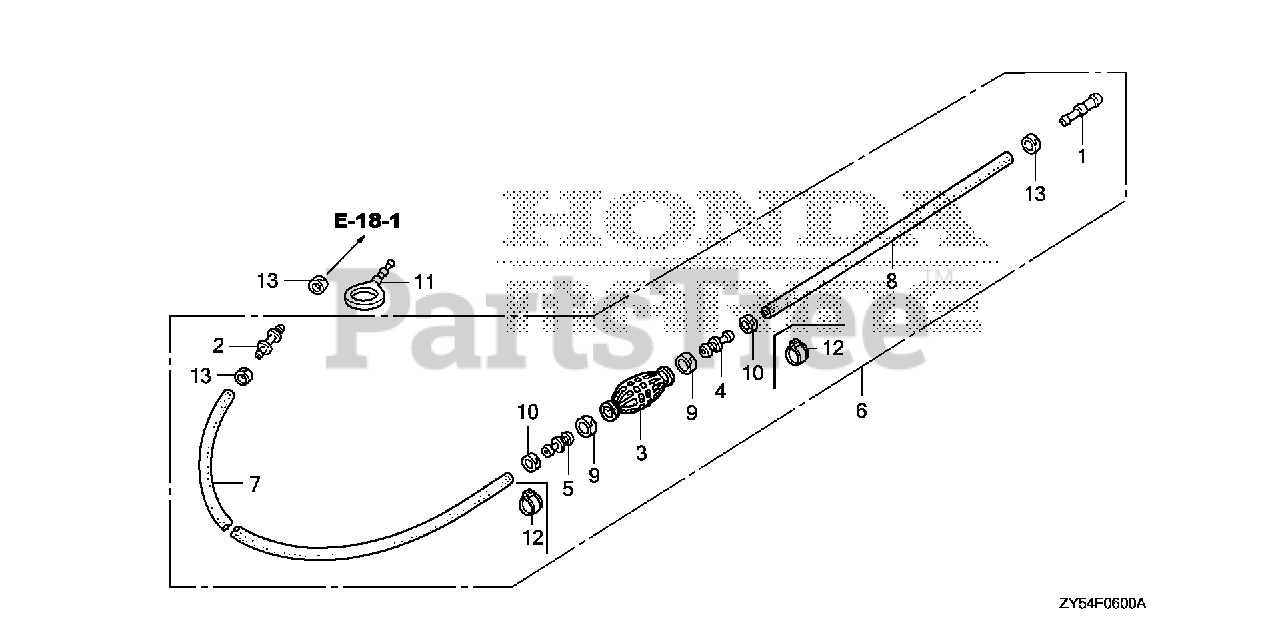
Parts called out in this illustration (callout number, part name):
1	JOINT, FUEL TUBE (JOINT TYPE)
2	JOINT, FUEL TUBE
3	BULB, PRIMER
4	VALVE, IN.
5	VALVE, OUTLET
6	TUBE ASSY., FUEL (JOINT TYPE)
6	TUBE ASSY., FUEL TANK (JOINT TYPE)(FKM)
7	TUBE, FUEL LONG (7.3X2000) (CONNECTOR TYPE)
7	TUBE, FUEL LONG (7.3X2000)
8	TUBE, FUEL SHORT (6.3X500) (CONNECTOR TYPE)
8	TUBE, FUEL SHORT (7.3X500) (CONNECTOR TYPE)
8	TUBE, FUEL SHORT (CONNECTOR TYPE)
9	BAND, TUBE CLIP (20MM)
10	BAND, TUBE CLIP (12.5MM)
11	PLUG, FUEL TUBE
12	CLAMP, FUEL TUBE (CONNECTOR TYPE)
12	CLAMP, FUEL TUBE (14.0) (CONNECTOR TYPE)
13	BAND, TUBE CLIP (12.5MM)
